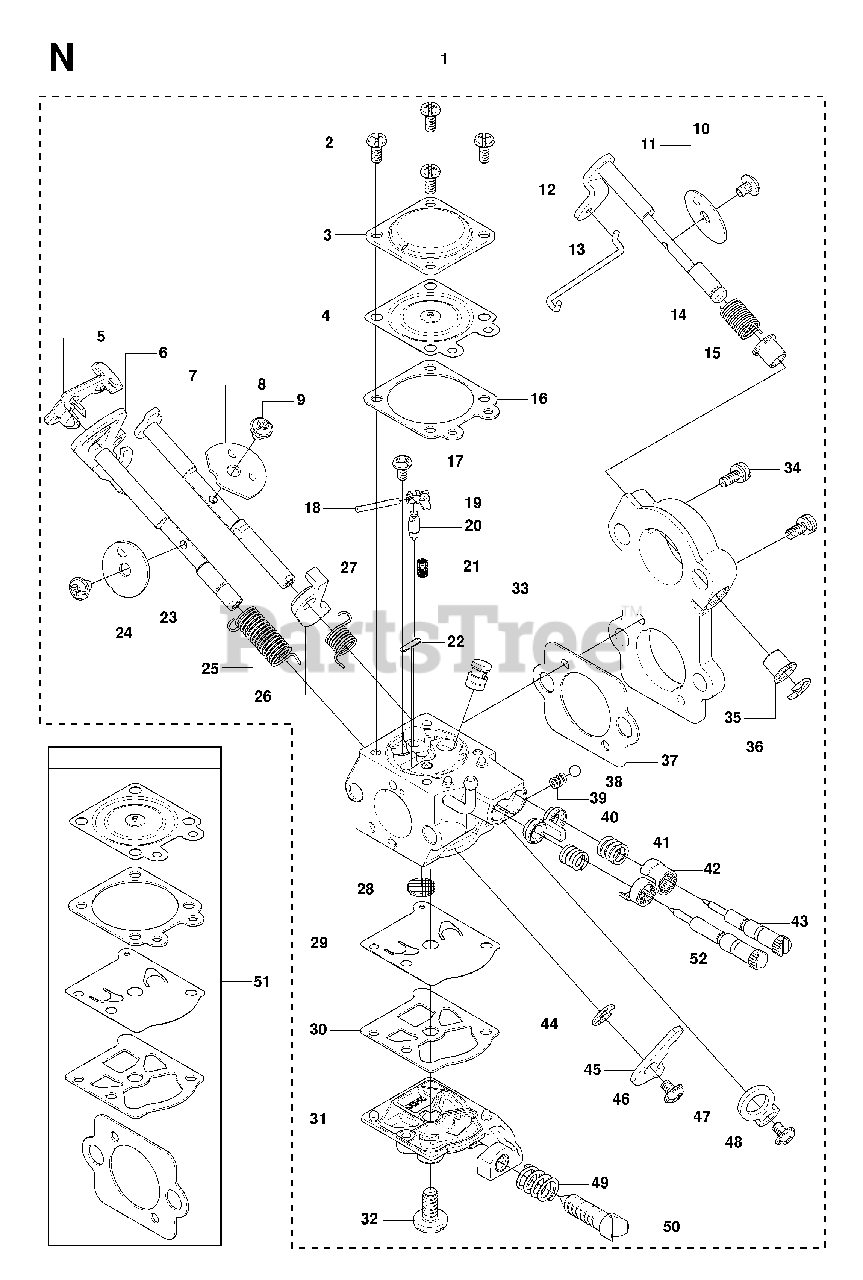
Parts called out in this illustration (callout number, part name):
1	CARBURETOR
3	DIAPHRAGM COVER
4	DIAPHRAGM
9	SCREW
10	SCREW
11	CHOKE FLAP
18	FULCRUM PIN
20	INLET NEEDLE
28	FUEL INLET SCREEN
29	DIAPHRAGM, FUEL PUMP
33	NOZZLE ASSY
36	E CLIP
42	LIMITER CAP
44	E CLIP
51	GASKET SET
